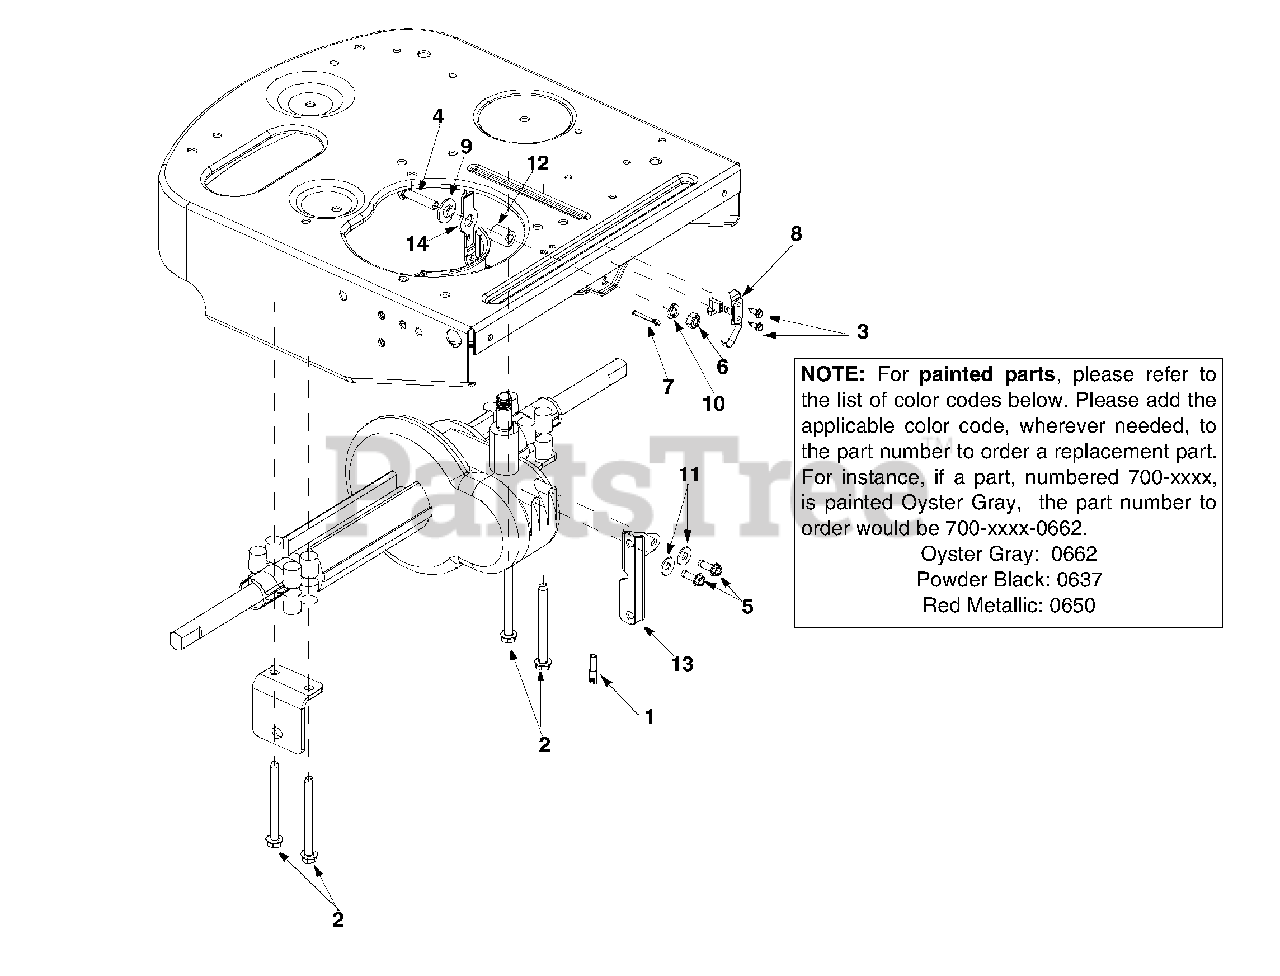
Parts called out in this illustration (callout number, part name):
1	Harness Assembly Adapter
2	Hex TT Screw 5/16-18 x 3.50
3	Hex Washer Head Self-Tap.Scew
4	Hex Screw 5/16-18 x 1.5 Gr. 5
5	Thd. Forming Scr. 1/4-20x .75
6	Hex Nut 5/16-18
8	Insulator Nut Plate
9	Shoulder Bushing
10	Lock Washer 5/16
11	Flat Washer
12	Spacer
